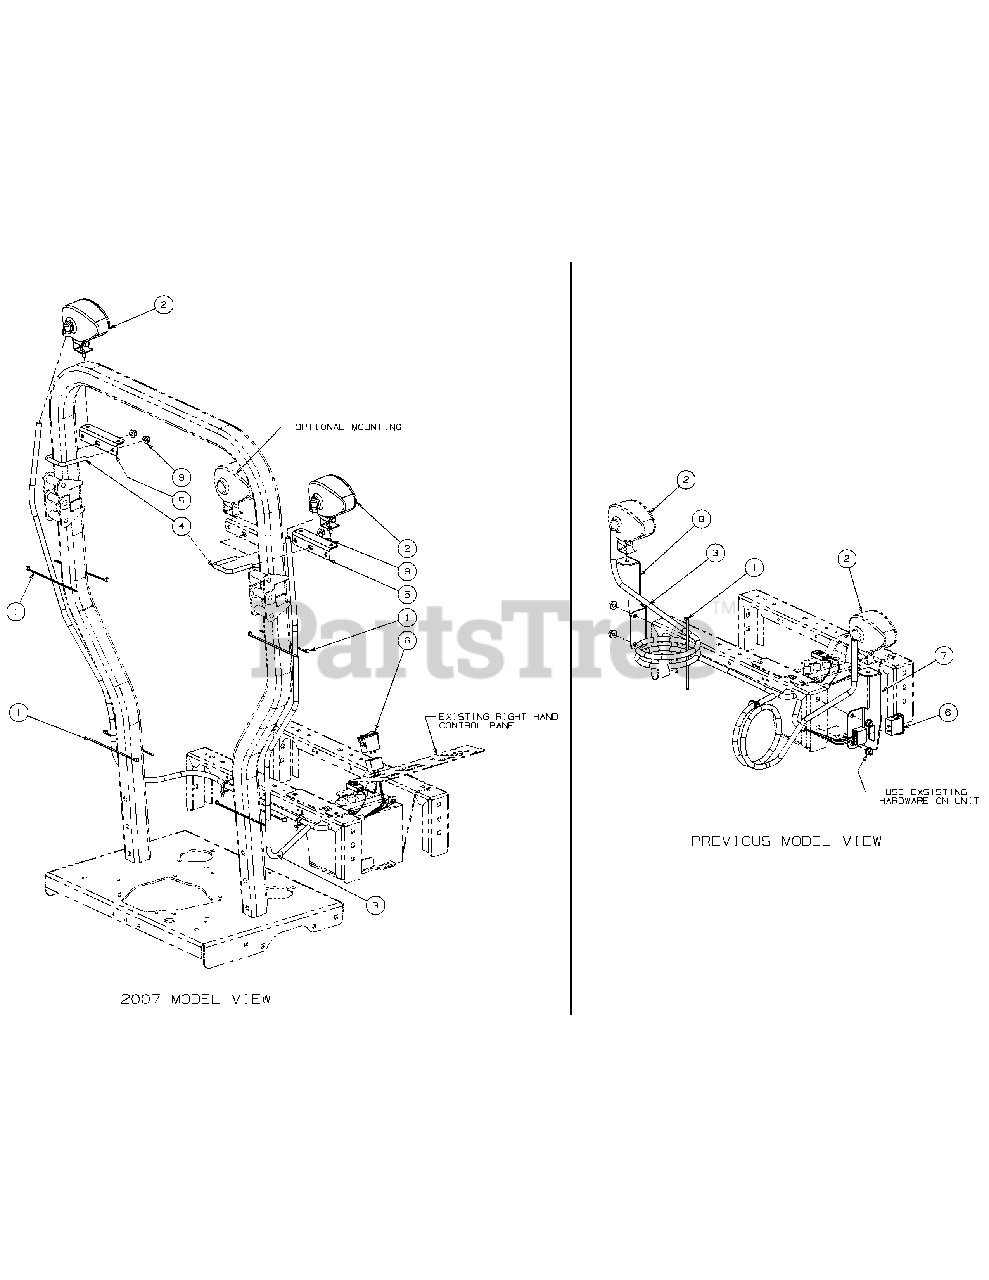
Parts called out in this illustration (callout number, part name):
1	Cable Tie
2	Oval Work Lamp
3	Wire Harness Assembly
4	U-Bolt, 3/8-16 x 2.125
5	Head Lamp Mount
7	Right Hand Lamp Bracket
8	Left Hand Lamp Bracket
9	Nylon Locknut, 3/8-16
